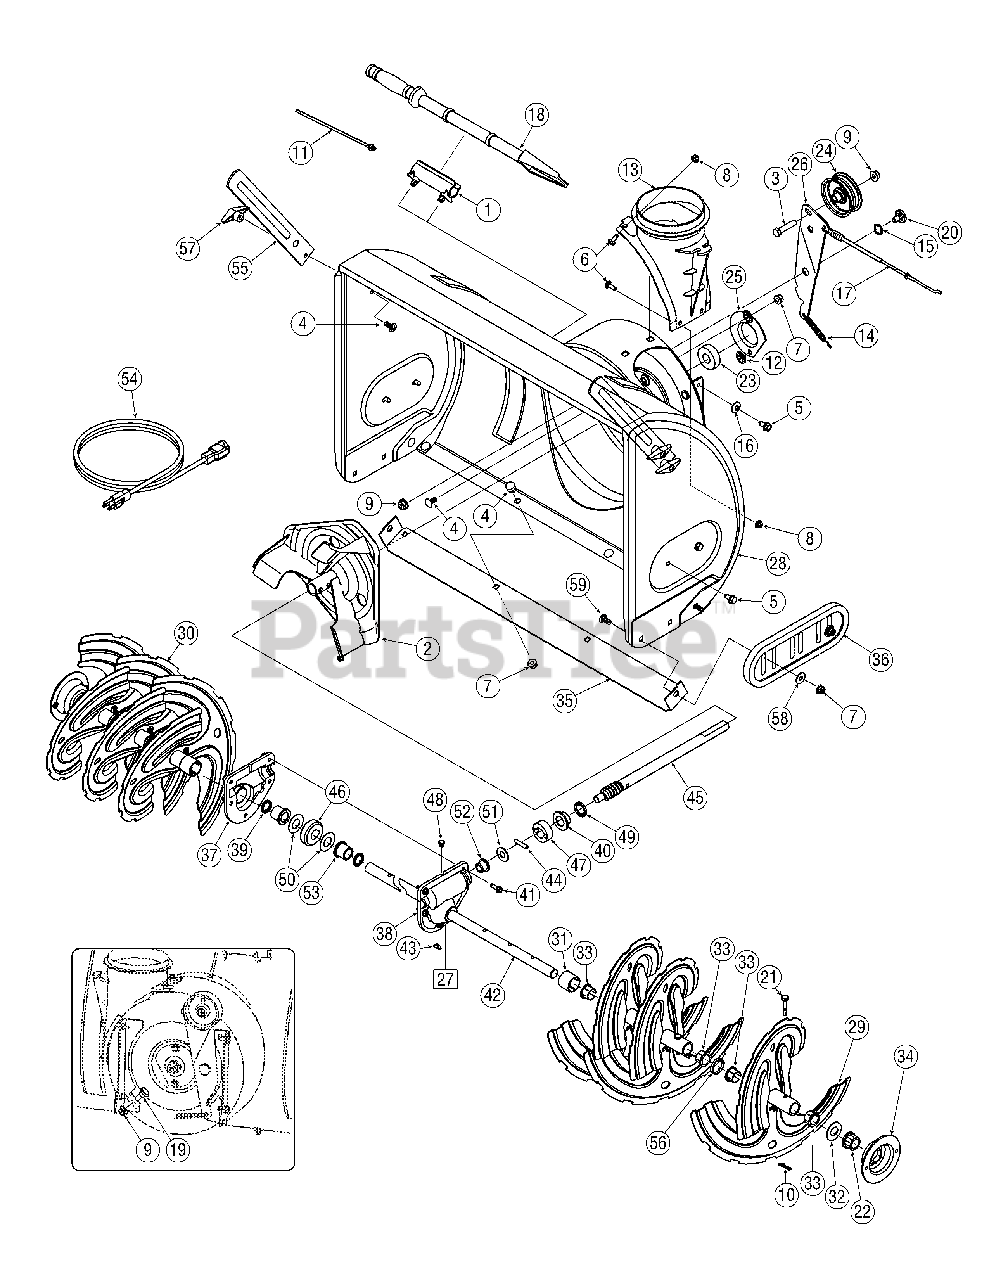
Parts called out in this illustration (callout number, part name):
1	Snow Removal Tool Mount
2	Impeller Assembly, 12" Dia.
3	Hex Screw, 3/8-16, 1.75, Gr5
4	Bolt, Carriage, 5/16-18, .750 Gr1
5	Screw, 5/16-18, 0.750
6	Screw, Carriage, 1/4-20, .750, Gr5
7	Nut, Flange Lock, 5/16-18, Nylon
8	Nut, Flange Lock, 1/4-20, Nylon
9	Nut, Flange Lock, 3/8-16, Nylon
10	Cotter Pin, Bow-tie
11	Cable, Tie, 3/16 x .05 x 7.4
12	Nut, Push-on, .25 Dia
13	Chute, Adapter 5" Dia
14	Spring, Extension, .38 OD x 4.59
15	Washer, Wave, .625 x .885 x .015
16	Washer, Bell, .340 x .872 x .060
17	Clutch Cable, Auger, 47.23"
18	Snow Removal Tool
19	Screw, Shoulder, .498 x .34, 3/8-16
20	Screw, Shoulder, .625 x .17, 3/8-16
21	Shear Pin, .25 x 1.50
22	Bearing, Hex Flange x .75 ID
23	Bearing, Ball, .75 ID x 1.85 OD
24	Flat Pulley, Idler, 2.75 OD
25	Housing, Bearing, 1.85 ID
26	Bracket, Auger Idler w/ Brake
27	Gearbox Assembly, Auger, 30"
28	Housing Assembly, Auger 30"
29	Spiral Assembly, LH
30	Spiral Assembly, RH
31	Spacer, 1.25 OD x .75 ID x 1.00
32	Washer, Flat, .76 x 1.49 x .06
33	Bushing, Flange, .80 ID x .91 OD
34	Housing, 1" Hex Bearing
35	Shave Plate, 2.25 x 29.66
36	Slide Shoe, Deluxe Polymer Reversible
36	Deluxe Polymer Reversible Shoe Kit
37	Housing, Auger, RH Reduced
38	Housing, Auger, LH Reduced
39	Seal, Oil, .750 x 1.00 x .125
40	Bearing, Flange, .75 x 1.0 x .59
41	Screw, Self-tapping, 1/4-20, 0.750
42	Axle, Auger, 30"
43	Key, Hi-pro 3/16 x 5/8
44	Pin, Dowel, .25 OD x 1.2
45	Shaft, Worm .75 OD
46	Gear, Worm 20T
47	Collar, Thrust
48	Plug, 1/4 x .437
49	Seal, Oil, .75 x 1 x .131
50	Washer, Flat, .760 ID x 1.5 OD
51	Washer, Flat, .51 x 1.12
52	Bearing, Flange, .75 x 1.0 x .925
53	Bearing, Flange, .75 x 1.00 x .975
54	Extension Cord, 110V
55	Drift Cutter
56	Spacer, 1.25 OD x .75 ID x 3/16
57	Wing Nut
58	Washer, Flat, .349 x .879 x .063
59	Scr., Crg., 5/16-18 x 1.00
